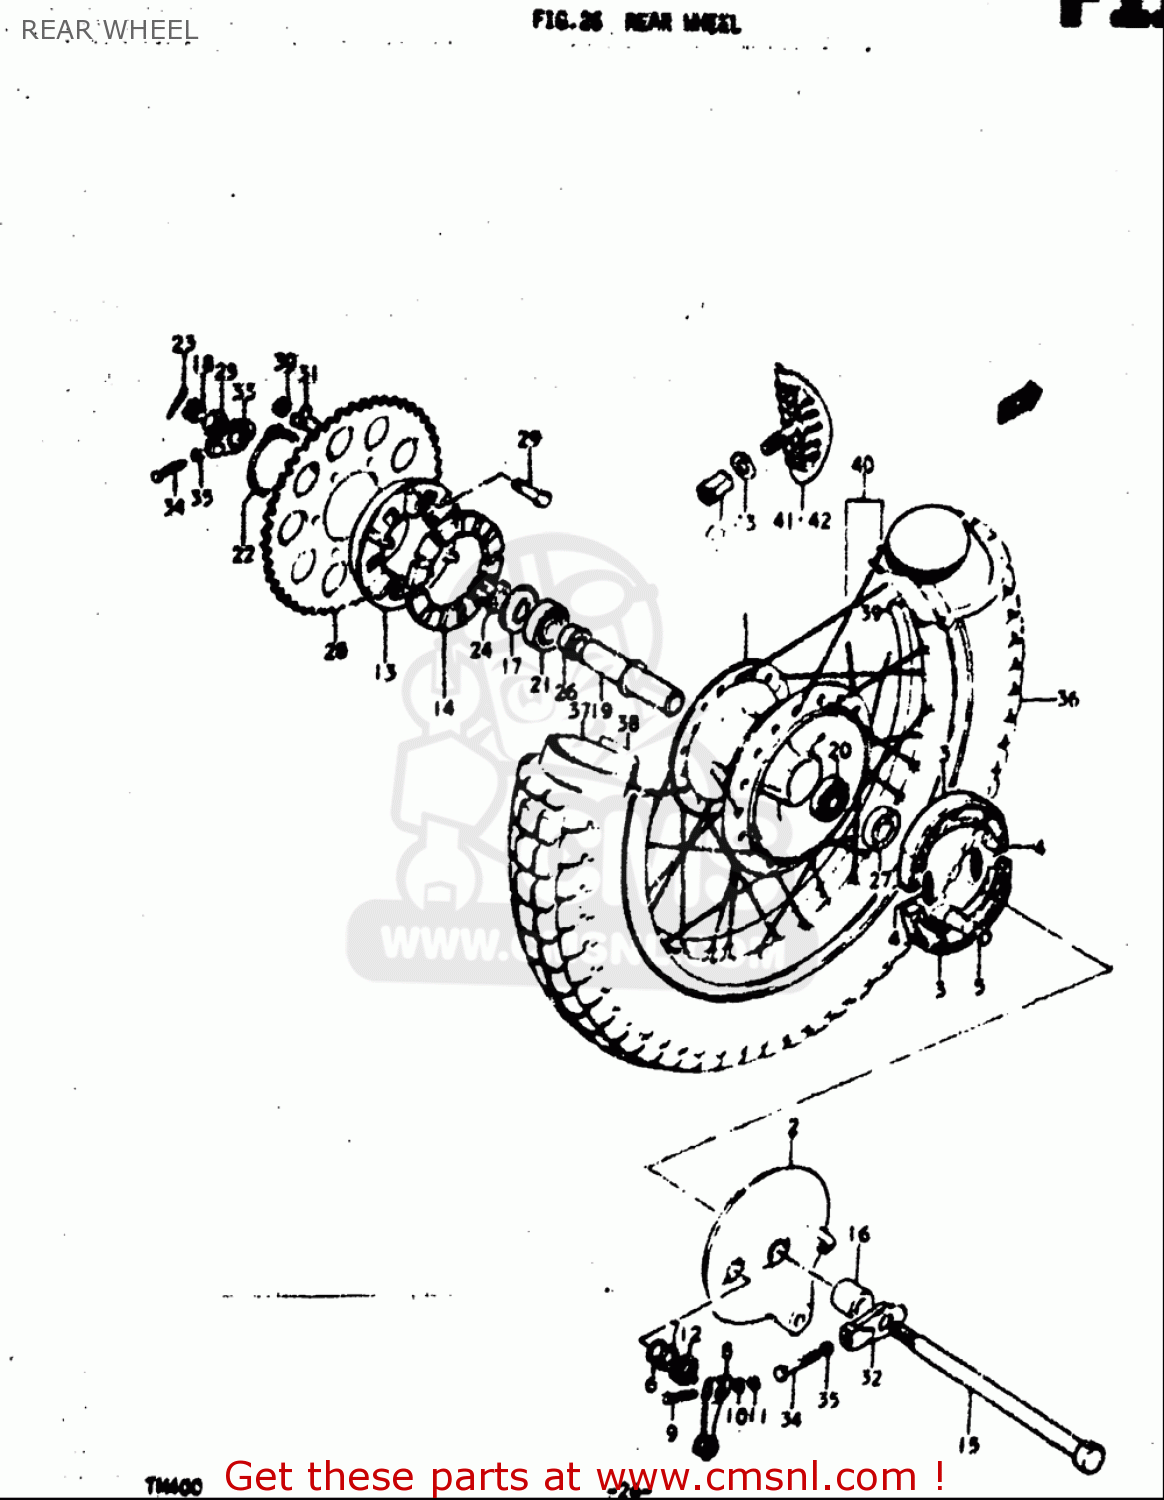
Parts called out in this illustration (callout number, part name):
3	SHOE SET,BRAKE (NAS)
4	SPRING,BRAKE SHOE
5	CAM,BRAKE
6	O RING(D:1.9,ID:18.8)
7	WASHER(15.5X24X1.6)
9	BOLT
10	WASHER
11	NUT
12	SPRING
14	ABSORBER,RR WHEEL HUB SHOCK
15	AXLE,REAR
18	NUT
19	SPACER,REAR HUB BEARING
20	BEARING(15X42X13)
21	BEARING
22	CIRCLIP
23	PIN 30X40
24	SPACER,REAR AXLE,LEFT
25	NUT
26	SPACER,REAR HUB BEARING
28	SPROCKET,RR
29	BOLT(8X33.5)
31	WASHER
32	ADJUSTER,CHAIN,R
33	ADJUSTER,CHAIN,L
34	BOLT(8X50)
35	NUT
40	SPOKE SET,RR
41	STOPPER,BEAD(1.85)
43	WASHER
